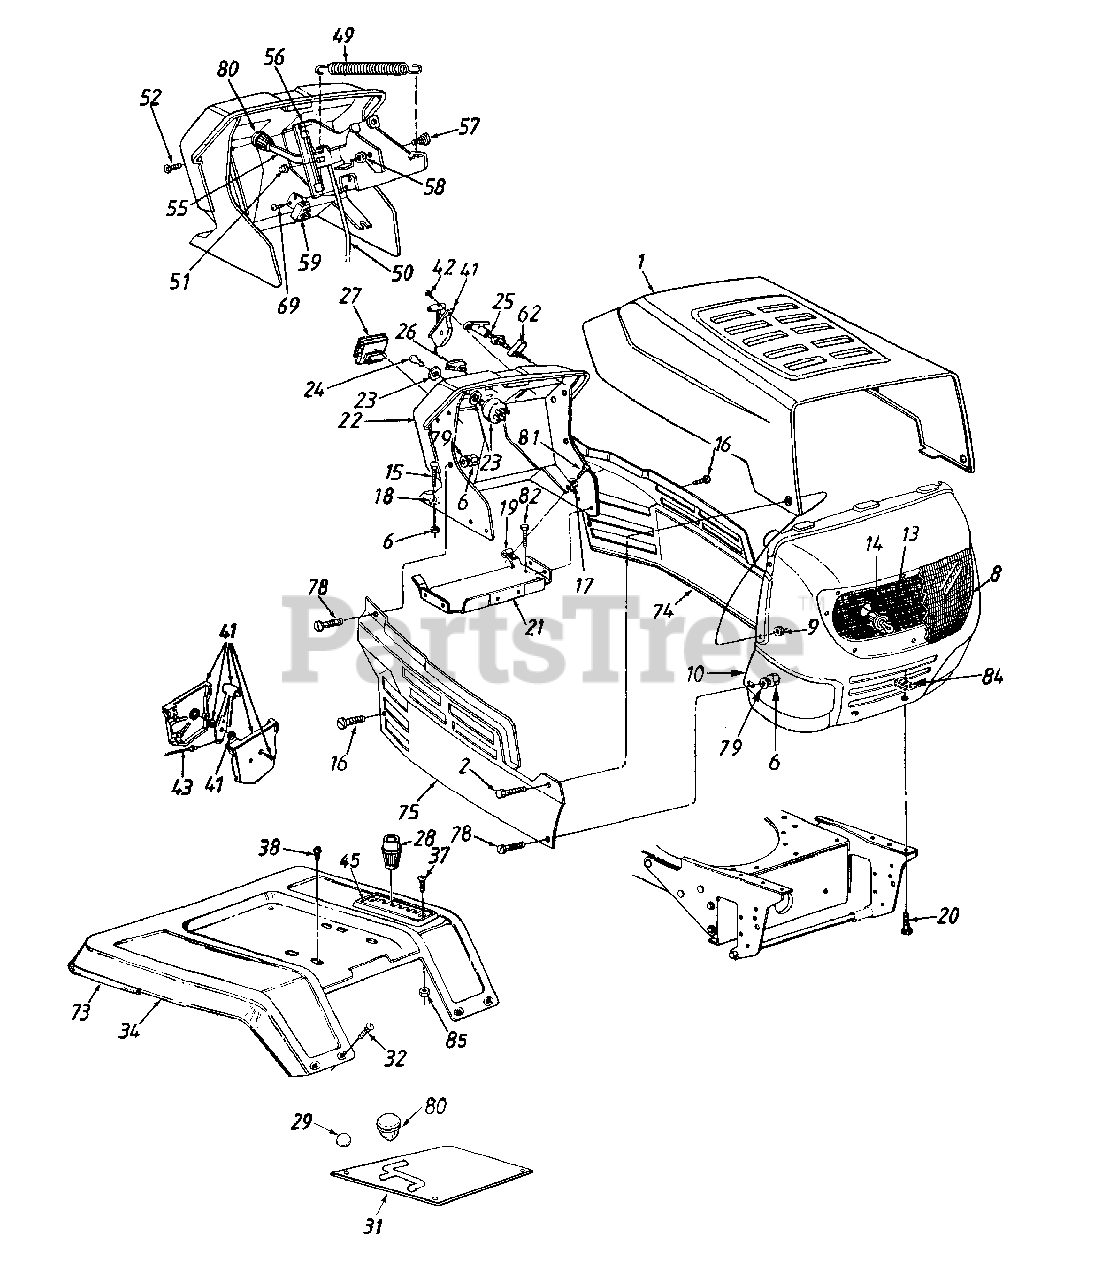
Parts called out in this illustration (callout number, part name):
6	Hex Nut 1/4-20 Thd.
8	Headlight Lens
9	Flange L-Nut 1/4-20 Thd.
13	Lamp
14	Socket
15	Carriage Bolt 1/4-20 x 1.0" Lg.
16	Hx Wash. Hd. TT-Tap Scr. 1/4-20 x.5" L
17	Fl-Wash. .281" I.D. x .73" O.D.
18	Bolt Retainer 1/4" I.D.
19	Speed Nut 1/4-20 Thd.
20	Hex Bolt 5/16-18 x .75" Lg.
23	Ignition Switch
24	Ignition Key
25	Choke Control
27	Ammeter (Optional)
28	Shift Knob
38	Hx Wash Hd. AB-Tap Scr. 5/16 x .75" L
41	Throttle Box Ass'y.
42	Truss Mach. AB-Tap Scr. #10 x .5" Lg.
43	Throttle Control Wire 35" Lg.
45	6-Speed Selector Plate (823)
49	Ext. Spring 5.06" Lg.
50	Deck Control Rod
51	Speed Nut 1/4" Rod
52	Torx Mach. Scr. 1/4 x .62" Lg.
55	PTO Lever
58	Hex L-Nut 5/16-18 Thd.
59	Safety Switch
62	Retainer Clip
69	Hx Wash. Hd. B-Tap Scr. #10 x .38" L.
73	Trim Strip 81" Lg.
79	Bell-Wash. 1/4" I.D.
80	Small Shift Knob
81	Hex TT-Tap Scr. 1/4-20 x .75" Lg.
82	Hex AB-Tap Scr. 1/4 x .62" Lg.
84	U-Nut 5/16-18 Thd.
85	Hex Sems Nut 1/4-20 Thd.
